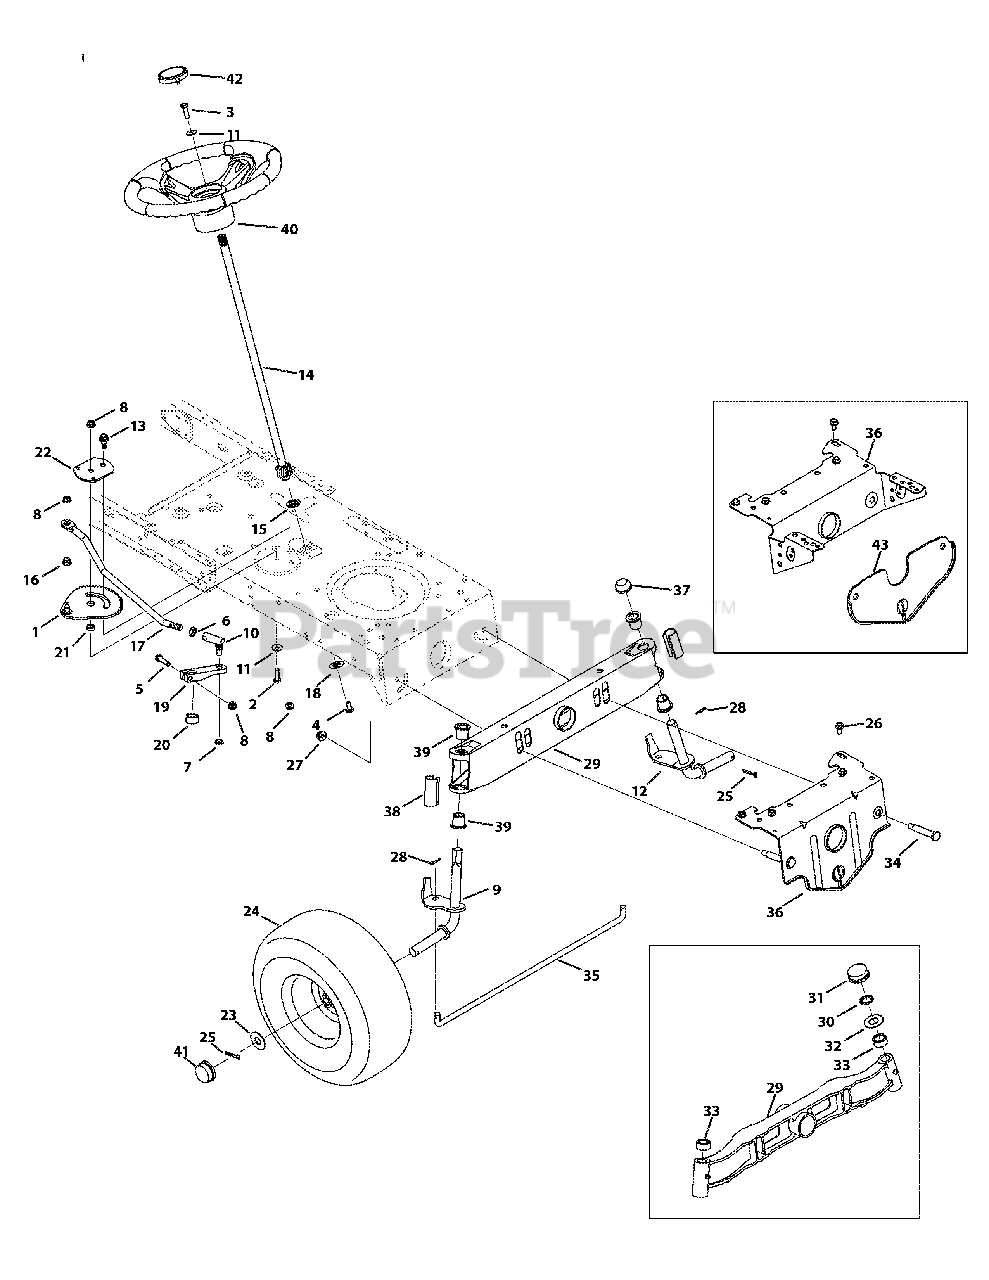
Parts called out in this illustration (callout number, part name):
1	Front Steering Gear Assembly
2	Hex Screw, 5/16-18 x 1.00, Standard
3	Hex Screw, 5/16-18 x 1.00, Lock
4	Machine Screw, 5/16-18 x .750
5	Hex Screw, 5/16-18 x 1.75
6	Jam Nut, 7/16-20
7	Jamlock Nut, 3/8-24
8	Flangelock Nut, 5/16-18
9	Front RH Axle
9	46" Front RH Axle
10	Ball Joint, 7/16-20
11	Bell Washer, .340 x .872 x .060
12	Front LH Axle
12	46" Front LH Axle
13	Shoulder Bolt, 5/16-18 x .435 x .350
14	Steering Shaft, 5/8 x 22.08
15	Flange Bearing, 5/8
16	Plastic Bushing, .380 ID
17	Steering Link
18	Cap, 1.25 x .16
19	Steering Block
20	Spacer, .71 x .125 x .56
21	Spacer, .322 x .625 .21
22	Gear Segment Stabilizer Plater
23	Flat Washer, .781 x 1.590
24	Wheel Assembly, 46" - Gray
24	Wheel Assembly, 46" - Yellow
24	Wheel Assembly, 42" and 38" - Gray
24	Wheel Assembly, 42" and 38" - Yellow
25	Cotter Pin, 5/32 x 1.25
26	Screw, 5/16-18 x .750
27	Flangelock Nut, 3/8-16
28	Cotter Pin, .125 x .75
29	Pivot Axle
30	Push Nut, 3/4
31	Hub Cap
32	Flat Washer, .78 x 1.59 x .060
33	Spacer, .71 x .125 x .56
34	Shoulder Bolt, 3/8-16 x .500 x 2.38
35	Fixed Rod
36	Pivot Bar Bracket
37	Push Cap, 3/4
38	Standard Axle Cap
39	Flange Bearing, .760 x .941 x 1.0
40	Steering Wheel
41	Hub Cap
42	Sprig Cap
43	Front Deck Hanger Bracket
